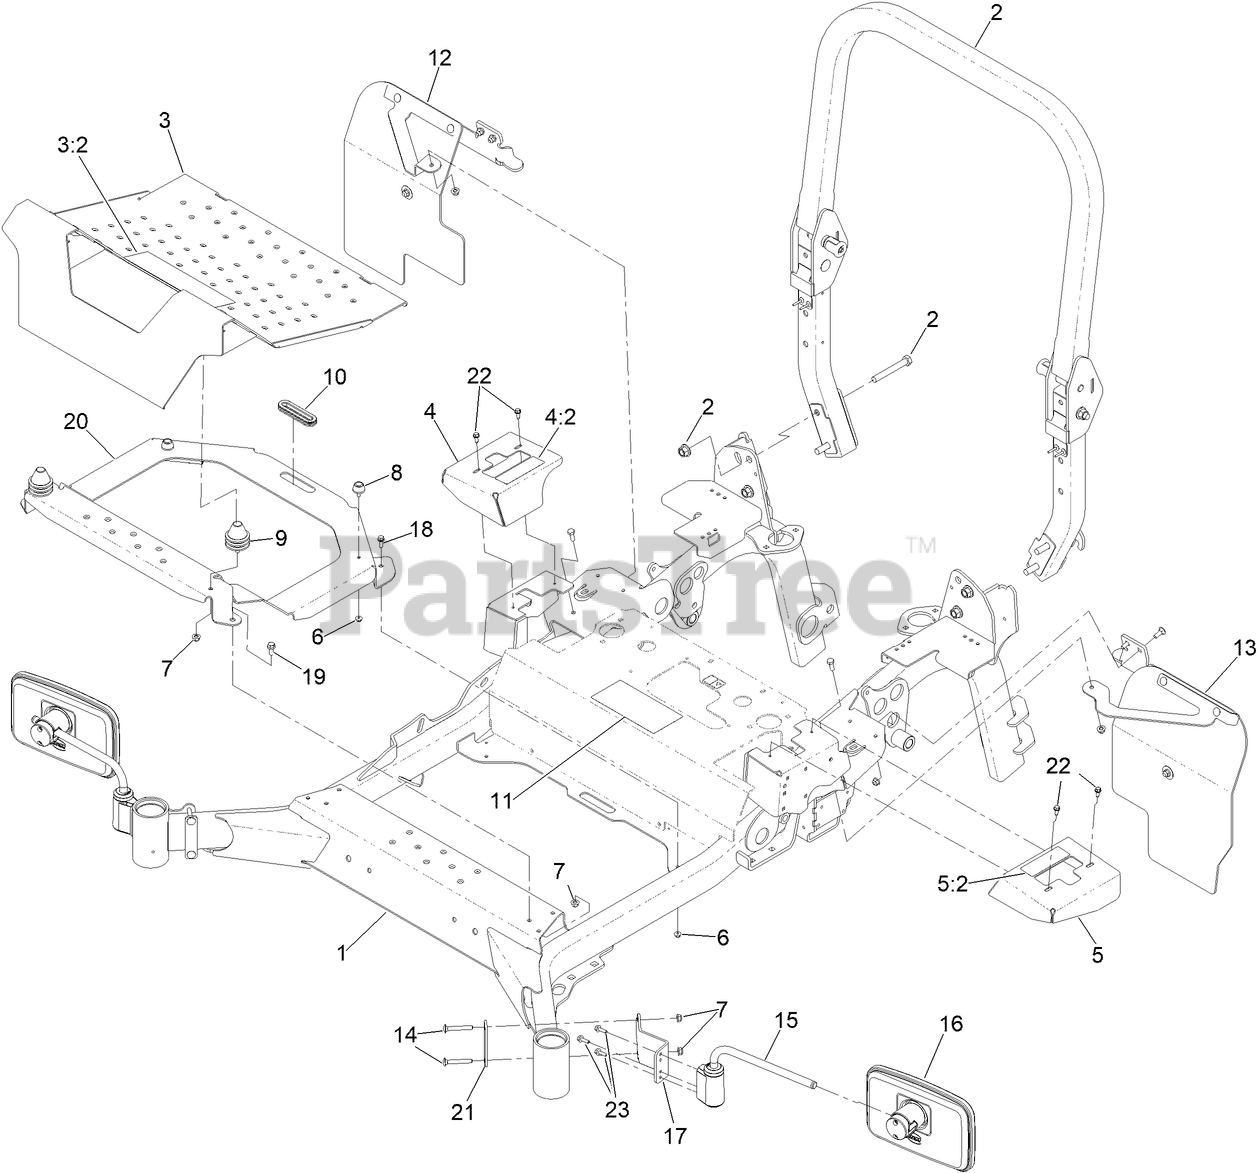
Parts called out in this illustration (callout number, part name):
1	MAINFRAME ASM, WD
2	ASM, ROPS-7500D DIESEL
3	PAN-FLOOR
3:2	DECAL-DANGER
4	ASM,MOTION CONTROL COVER W/DECAL RH
4:2	DECAL-RH MOTION CONTROL
5	ASM,MOTION CONTROL COVER W/DECAL LH
5:2	DECAL-LH MOTION CONTROL
6	NUT-HF
7	NUT-HF, NI
8	BUMPER-RUBBER
9	ISOLATOR
10	GROMMET-RUBBER
11	DECAL-SERVICE AID
12	ASM, RH MUD FLAP
13	ASM, LH MUD FLAP
14	BOLT-CARR
15	MIRROR ARM
16	MIRROR, 144
17	PLATE-MIRROR MOUNT
18	SCREW-HHF
19	SCREW-HHF
20	BRACKET, FLOOR PAN RISER
21	BRACKET-MIRROR
22	SCREW-HWH
23	SCREW-HHF
